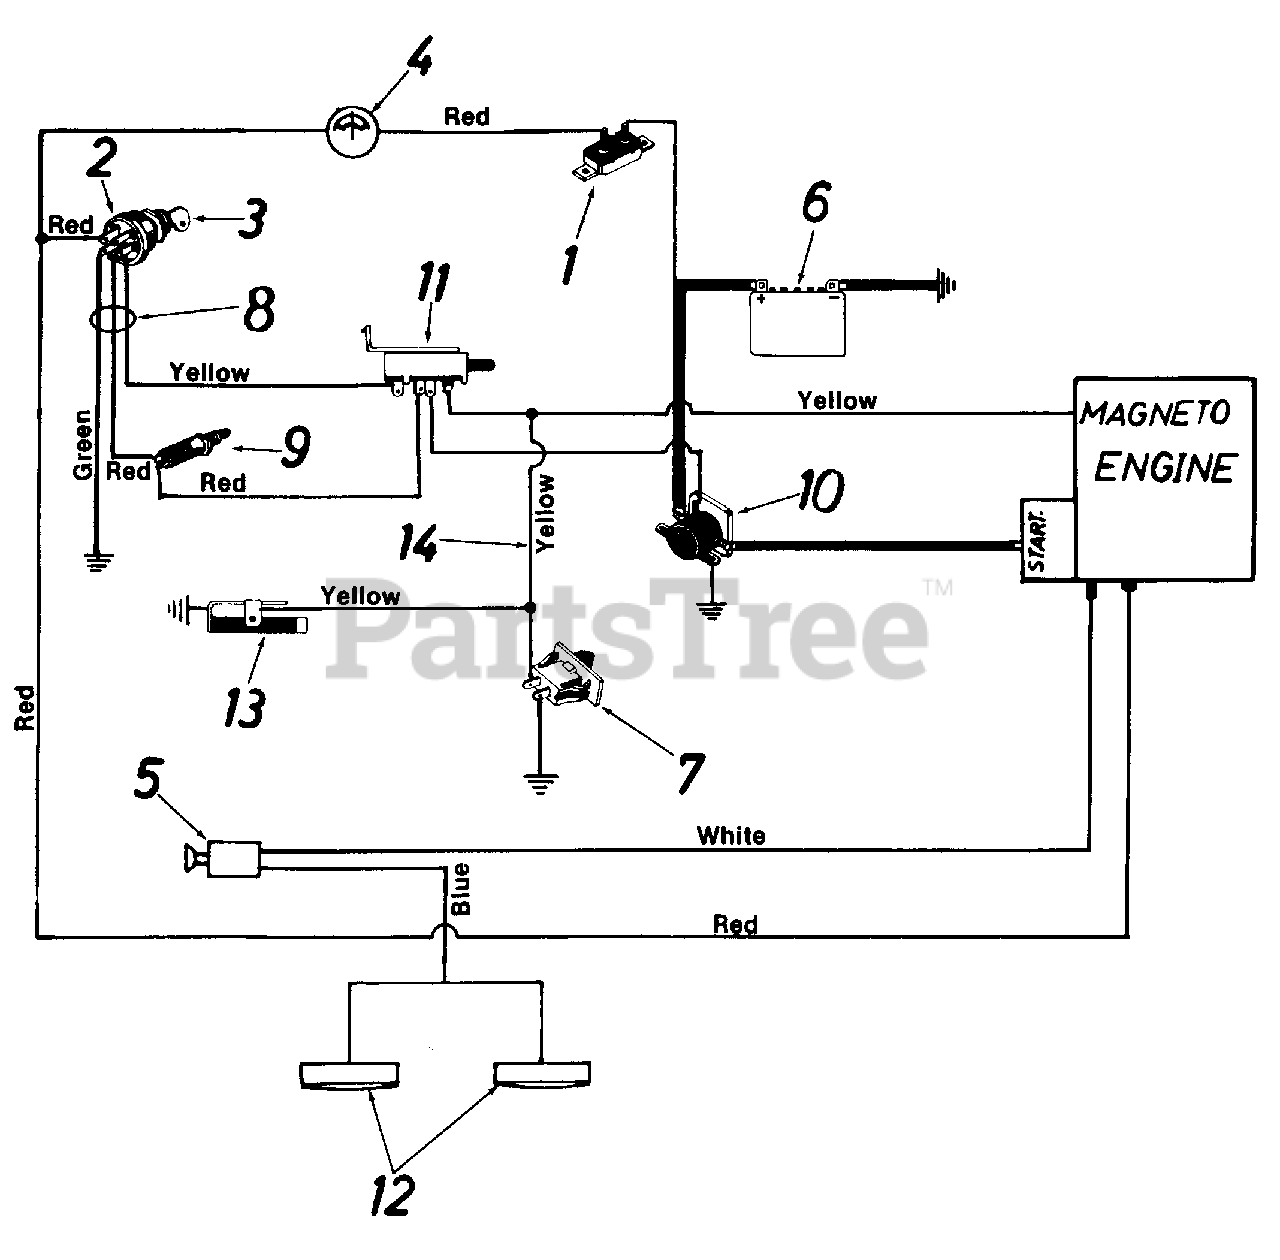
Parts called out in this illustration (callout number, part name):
1	Circuit Breaker
2	Ignition Switch
3	Ignition Key
4	Ammeter
5	Headlight Switch
6	Battery
7	Safety Switch
8	Wiring Harness
9	Safety Switch
10	Solenoid
11	Safety Switch
12	Headlight
13	Spring Switch
14	Wire Lead
